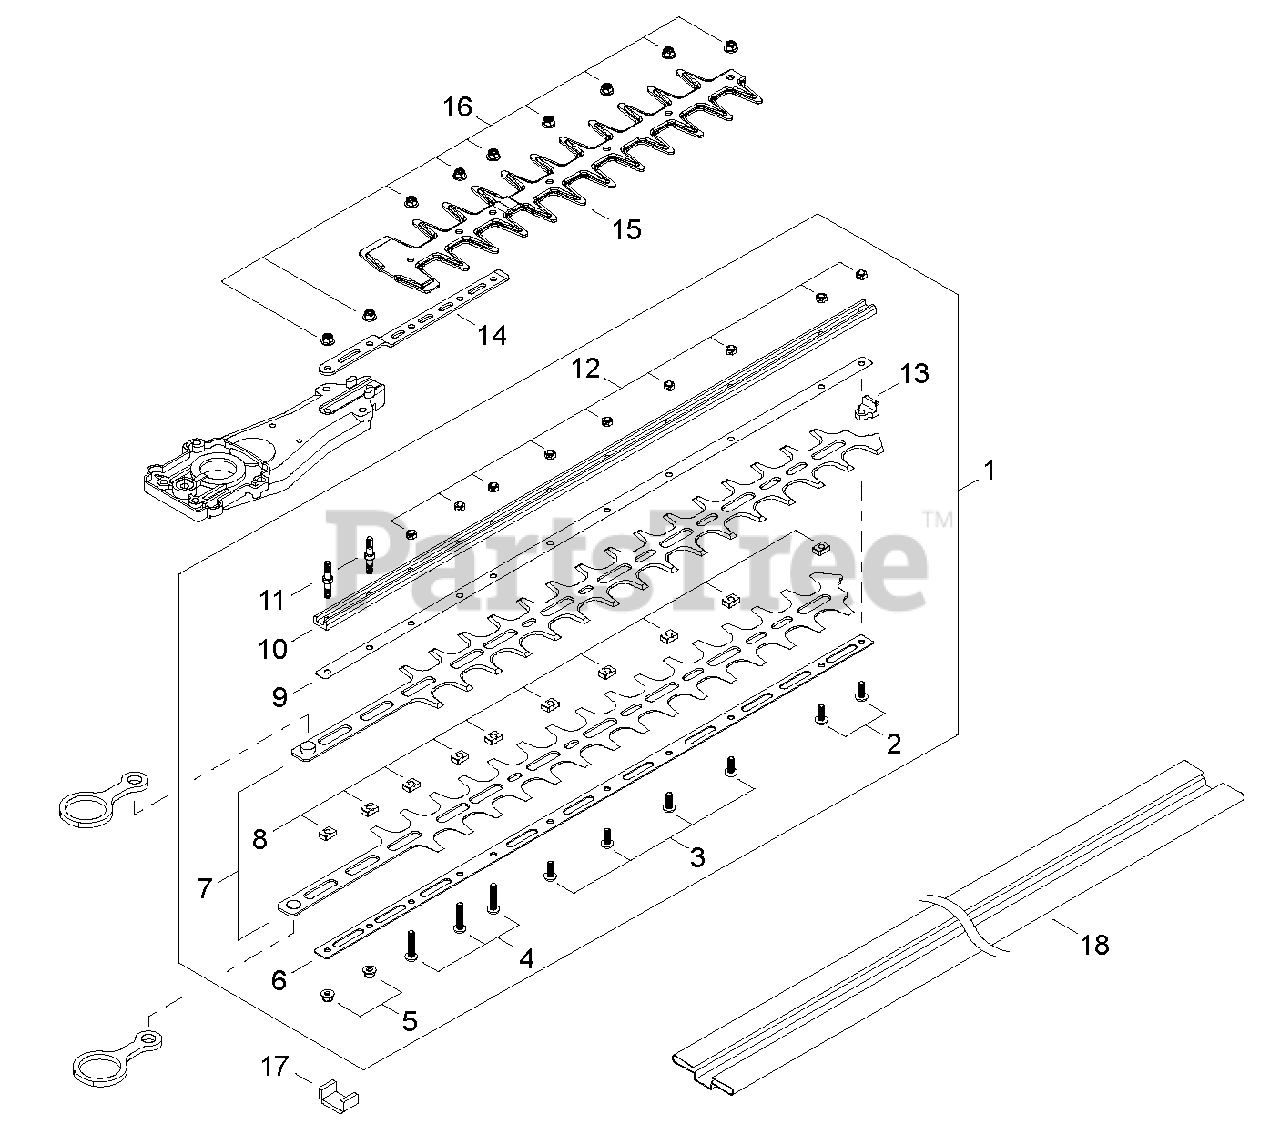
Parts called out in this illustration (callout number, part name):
1	BLADE KIT - 24" (60cm)
2	SCREW - 5X14
3	SCREW - 5X22
4	SCREW - 5X25
5	NUT - 5
6	PLATE - LOWER
7	BLADE - 24" (60cm)
8	SPACER
9	PLATE - UPPER
10	SUPPORT, BLADE - 24" (60cm)
11	STUD - 5
12	LOCKNUT - 5
13	BLOCK
14	BRACKET, CUTTER
15	SHIELD, BLADE
16	NUT - 5
17	SEAL, FELT
18	COVER, BLADE - 24" (60cm)
